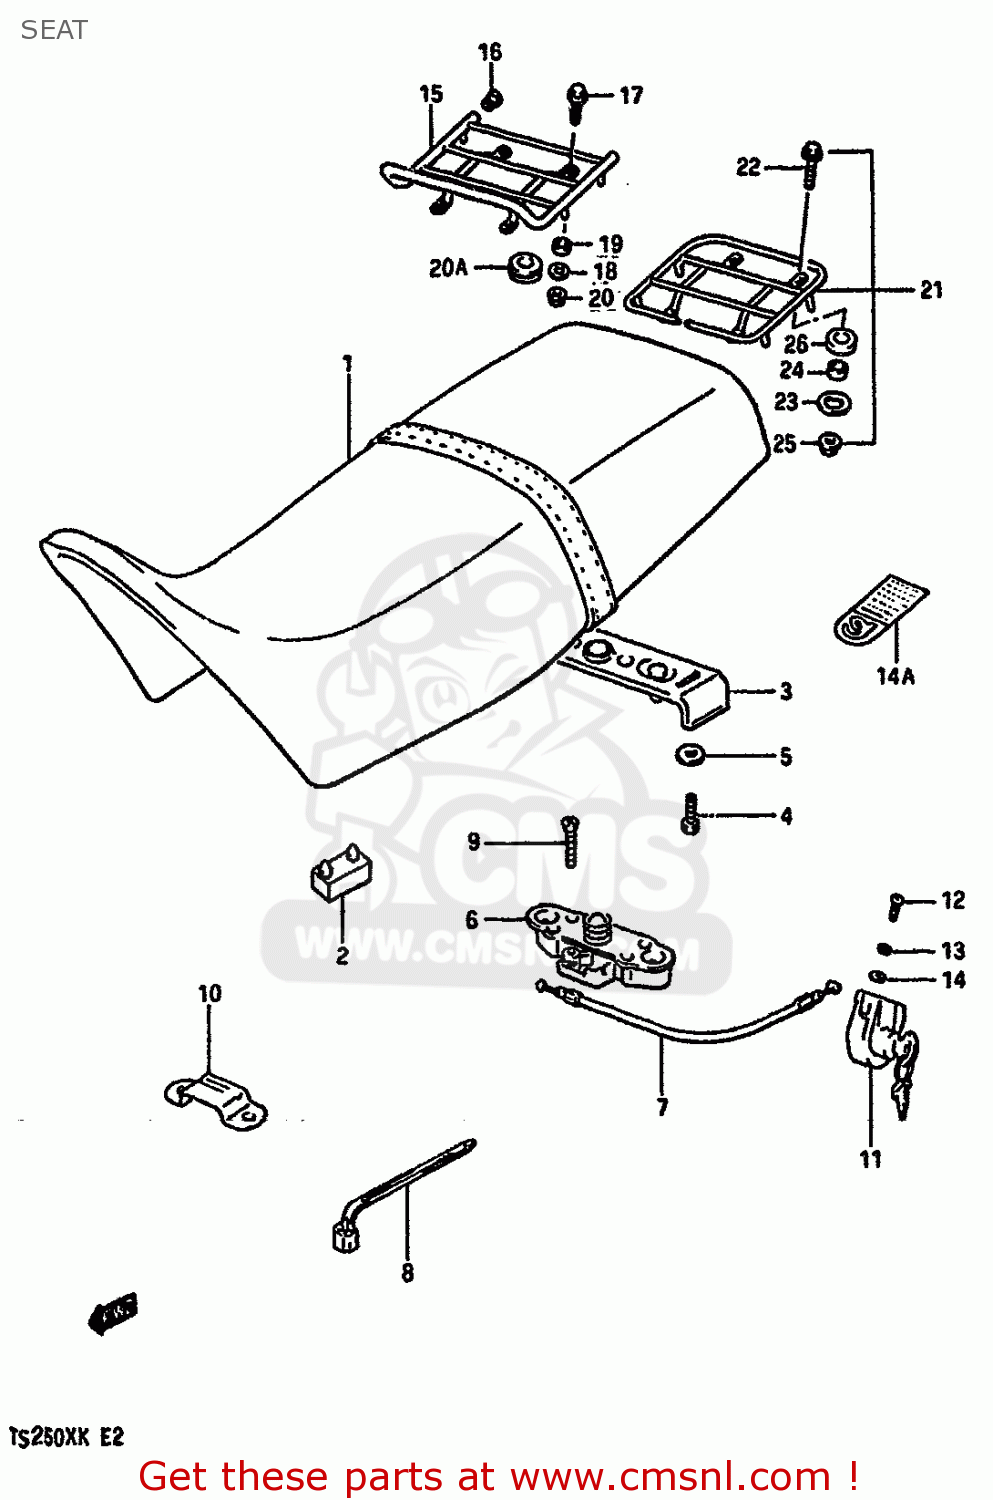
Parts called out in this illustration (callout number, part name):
1	SEAT ASSY (BLUE)
2	CUSHION
3	STRIKER,SEAT LOCK
4	BOLT,M6X1X20
5	WASHER,LOCK
6	LOCK ASSY,SEAT STRIKER
7	CABLE,SEAT LOCK
8	CLAMP(L:95)
9	SCREW,6X30
10	PLATE,SEAT FR HOOK
11	LOCK ASSY,SEAT
12	SCREW
13	WASHER,LOCK
14	WASHER
14A	LABEL,ASBESTOS WARNING
15	HANDLE,PILLION RIDER
16	PLUG
17	BOLT
18	WASHER(6.5X18X1)
19	SPACER
20	NUT
20A	CUSHION
21	CARRIER SET,SUPPORT
22	BOLT
23	WASHER(6.5X18X1)
24	SPACER
25	NUT 6MM
26	CUSHION
